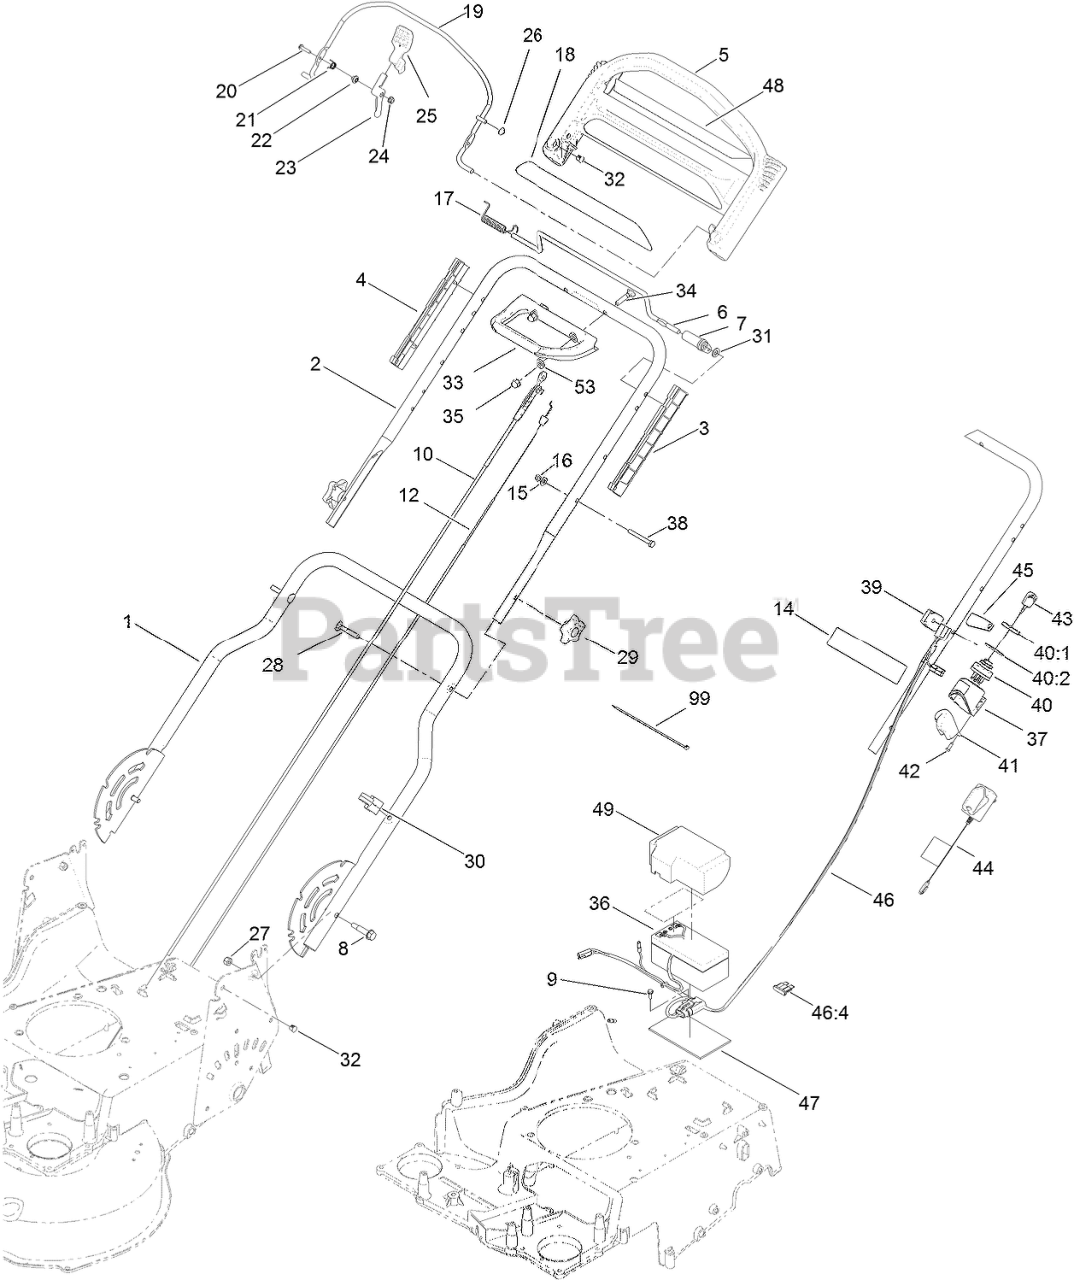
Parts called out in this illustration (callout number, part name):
1	HANDLE-LOWER
2	HANDLE-UPPER
3	GUIDE-LH
4	GUIDE-RH
5	HANDLE-CONTROL
6	BAR-CONTROL, TRACTION
7	LEVER-TRACTION
8	BOLT-SHOULDER, HHF
9	SCREW-TAPTITE
10	CABLE-BRAKE, BBC
12	CABLE-TRACTION
14	DECAL-WARNING
15	WASHER-FLAT
16	NUT-LOCK, NI
17	Spring-Torsion
19	BAIL-BRAKE
20	SCREW-HWH
21	SPRING-TORSION
22	SPACER
23	LEVER
24	NUT-LOCK, FLANGE
26	NUT-SPEED
27	NUT-LOCK, NI
28	SCREW-HANDLE
29	KNOB-HANDLE
30	GUIDE-CABLE
31	WASHER-PLAIN
32	Plug-Dome
33	HANDLE-ASSIST, TRACTION
34	SCREW-HANDLE, LOCK
35	NUT-ACORN
36	BATTERY-WET
37	HOUSING-SWITCH, KEY
38	SCREW-HH
39	ANCHOR-CABLE, UPPER
40	SWITCH-STARTER
40:1	NUT-HH
40:2	WASHER-TOOTH, INTERNAL
41	COVER-SWTCH
42	SCREW-PPH
44	CHARGER-BATTERY
45	DECAL-SWITCH, IGNITION
46	HARNESS-WIRE
46:4	FUSE-40 AMP
47	FOAM-BATTERY
48	DECAL-ASSIST, TRACTION
49	COVER-BATTERY
53	WASHER-PLAIN
99	TIE-CABLE
